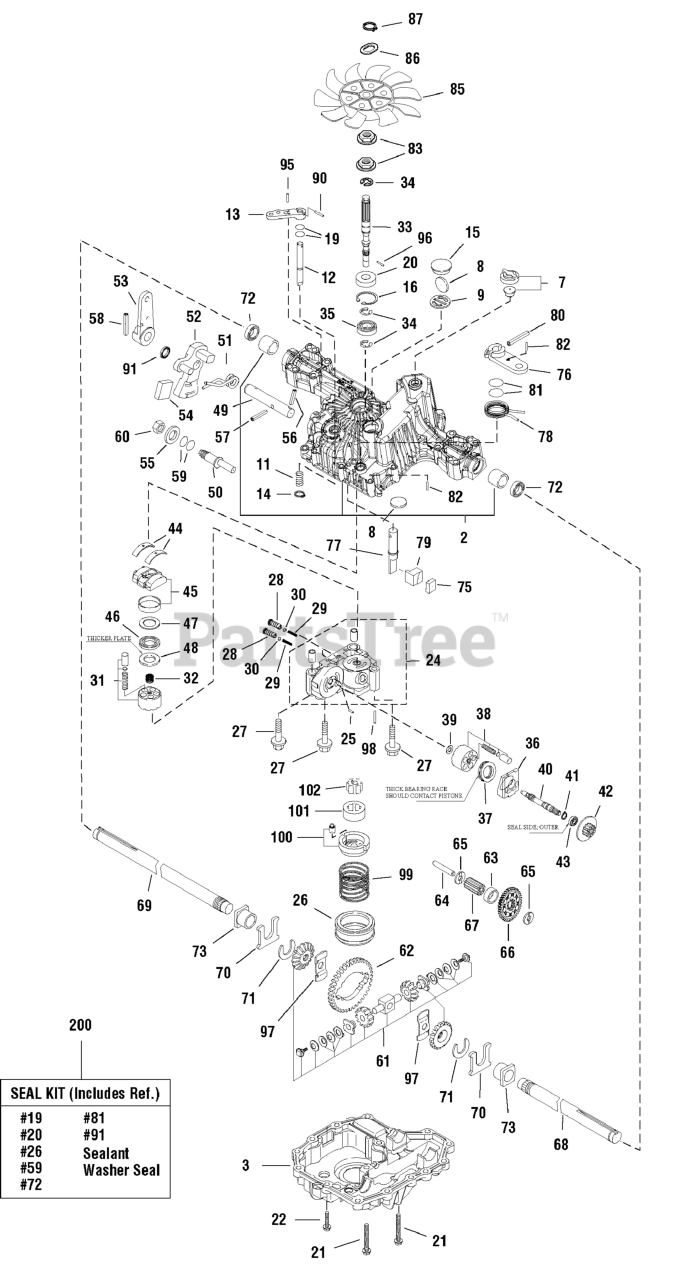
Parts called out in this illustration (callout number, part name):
2	*HOUSING ASSEMBLY, Upper
3	HOUSING, LOWER
7	VENT VALVE 15
8	MAGNET, K50
9	*HOLDER, Magnet
12	SHAFT, Bypass
13	LEVER, Bypass
15	SEALING CAP
19	O-RING, 1A P10A
21	SCREW, Tapping
22	*SCREW, Tapping
24	CASE, CENTER
25	PIN 3 x 9.8
27	BOLT 10 x 75
28	VALVE, IDS 1.0
29	SPRING, IDS
30	*BALL, 3/16
31	*CYLINDER BLOCK ASSEMBLY
32	SPRING, PUMP
33	SHAFT, PUMP
34	RING E15
37	*BEARING, Thrust
38	BLOCK, CYLINDER
39	WASHER 12 x 24 x 1
40	SHAFT, MOTOR
42	GEAR, MOTOR
43	BEARING 6202UC3
44	THRUST METAL
45	SWASH PLATE ASSEMBLY
46	THRUST PLATE B
47	BEARING K81105
48	THRUST PLATE A
49	*SHAFT, Control
50	*FULCRUM, ECCENTRIC
51	SPRING, Torsion
52	LEVER, Control
53	ARM, Control
54	JERKY PLATE
56	PIN, COTTER
57	PIN, SPRING
58	PIN 6.0A x 4.0
59	PACKING
61	GEAR & PINION ASSEMBLY
62	*GEAR, FINAL CONTR TRAC
63	COLLAR, PINION
64	*SHAFT, Reduction
65	WASHER, 12 x 32 x 3.2
66	GEAR, Reduction
67	PINION, Final
68	SHAFT, AXLE, Left
69	SHAFT, AXLE, Right
70	WASHER, Thrust
72	SEAL 19 x 32 x 8
73	BUSHING 19 x 21
75	SHOE, Brake
77	SHAFT, Brake
78	SPRING, RETURN B
79	BRAKE, Actuator
81	PACKING
82	PIN, Spring
83	COLLAR, Spline
90	PIN 3.0A x 20
97	WASHER, THRUST DIFF
98	PIN, 3.0A x 18
99	*SPRING, Charge
100	CHARGE PUMP CASE ASSEMBLY
200	SEAL KIT, K57
